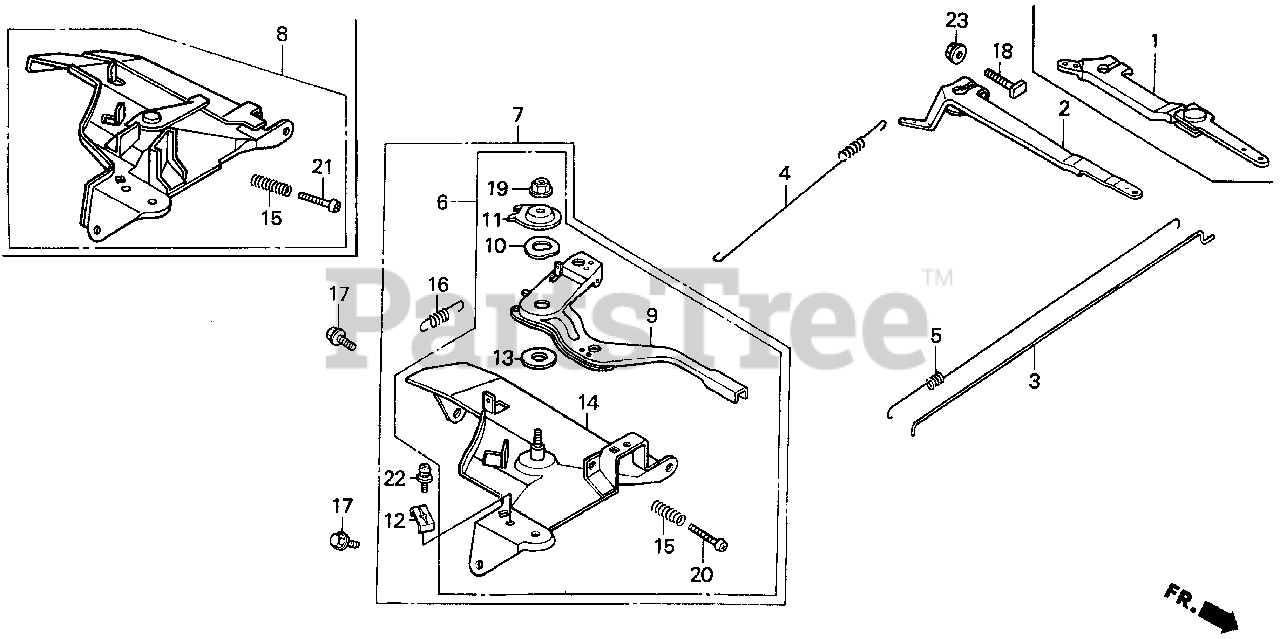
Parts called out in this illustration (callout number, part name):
2	ARM, GOVERNOR
3	ROD, GOVERNOR
4	SPRING, GOVERNOR
5	SPRING, THROTTLE RETURN
7	CONTROL ASSY. (REMOTE)
9	LEVER, CONTROL
10	SPRING, LEVER
11	WASHER, CONTROL LEVER
12	HOLDER, CABLE
13	SPACER, CONTROL LEVER
14	BASE, CONTROL
15	SPRING, CONTROL ADJUSTING
16	SPRING, CABLE RETURN
17	BOLT, FLANGE (6X12) (CT200)
18	BOLT, GOVERNOR ARM
19	NUT, SELF-LOCK (6MM)
20	SCREW, PAN (5X28)
22	SCREW, PAN (5X16)
22	SCREW-WASHER (5X16)
23	NUT, FLANGE (6MM)
